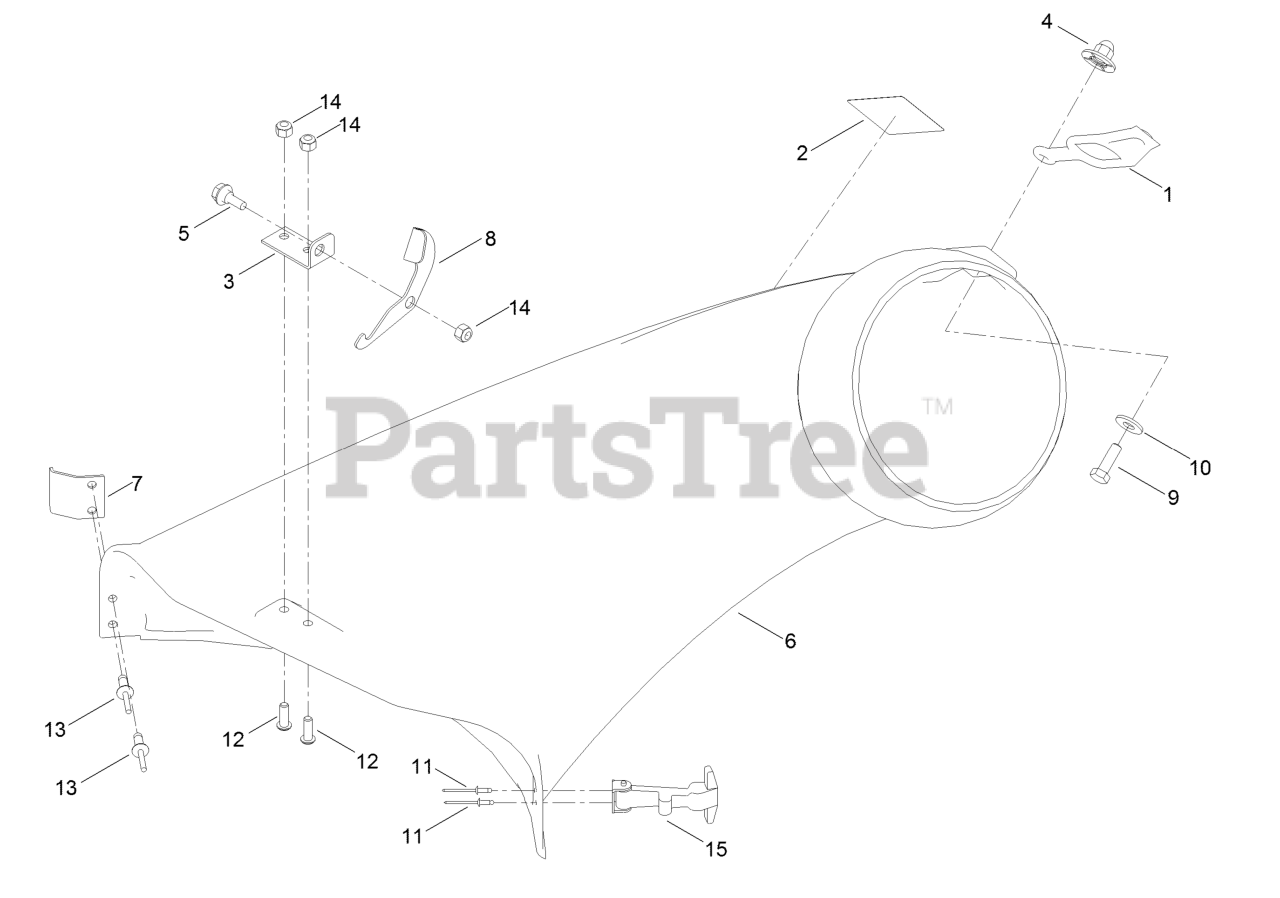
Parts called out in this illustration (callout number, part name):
1	Retainer-Duct
2	Decal-Danger
3	Plate-Pivot
4	Nut-Impeller
5	Screw-Shoulder, HHF
6	42 Inch Bagger Boot
7	Bracket-Elbow
9	Screw-HH
10	Washer-Flat
11	Rivet-Pop
12	Screw-HSBH
13	Rivet-Blind
14	Nut-Lock, NI
15	Handle ASM
